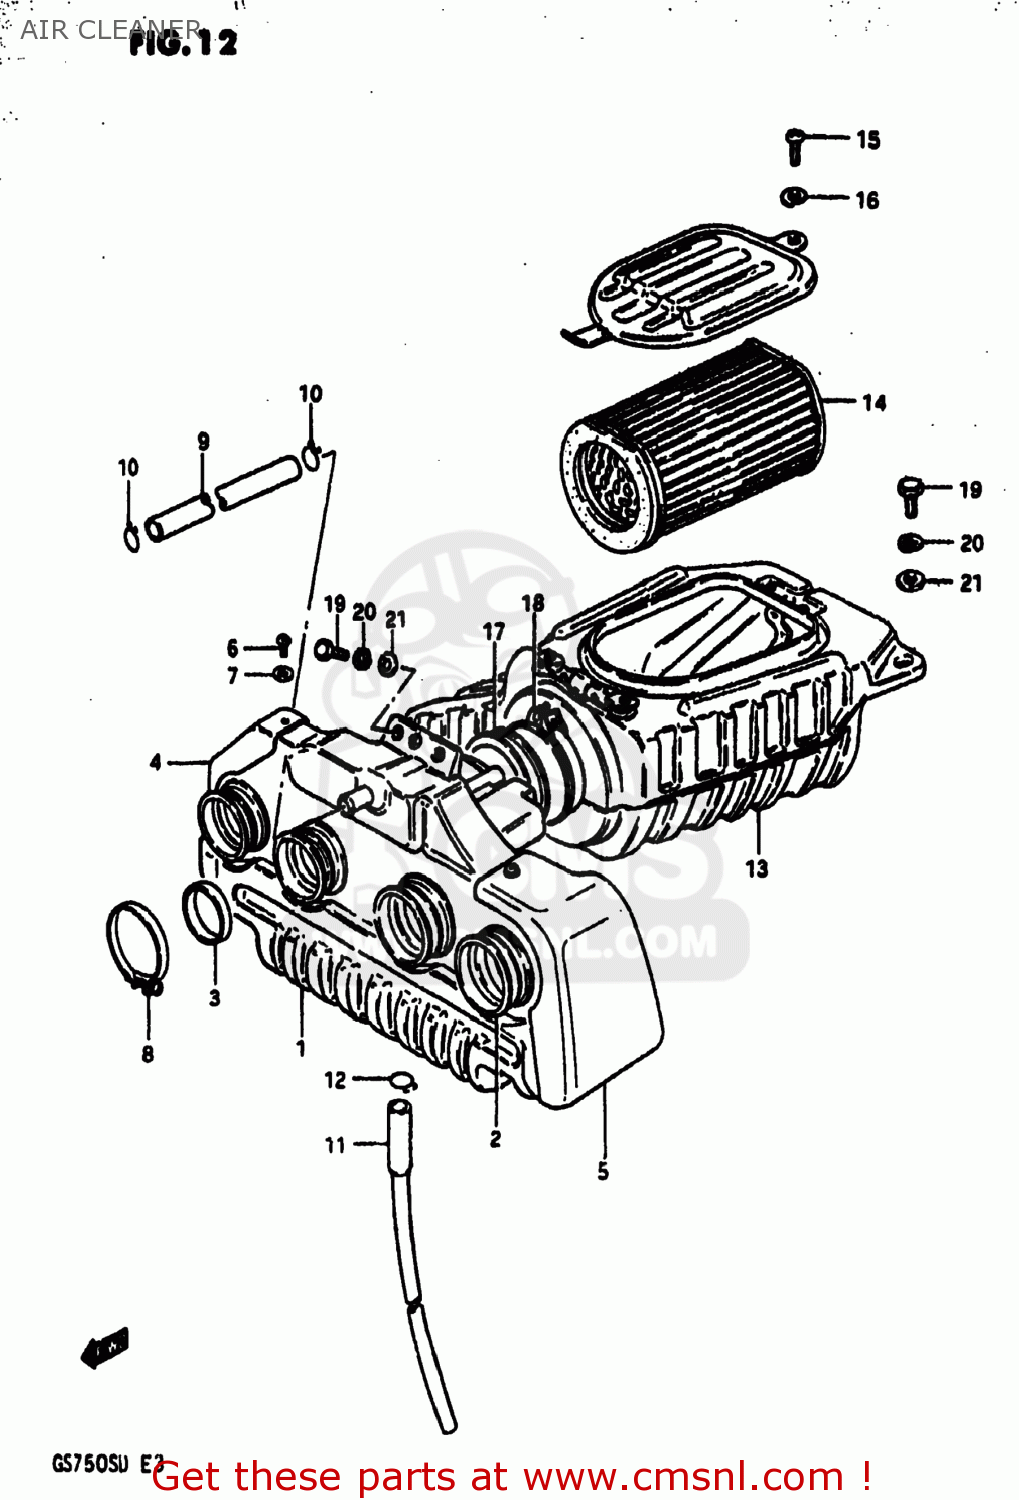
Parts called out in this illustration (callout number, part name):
1	CASE COMP,AIR CLEANER
2	TUBE,OUTLET
3	RING,CARBURETOR AIR INLET HOSE
4	COVER,AIR CLEA
5	COVER
6	SCREW 4X6
7	WASHER
8	CLAMP
9	TUBE,BREATHER
10	CLIP
11	DRAIN TUBE
12	CLIP
13	CLEANER SET,AIR,REAR
14	FILTER,AIR CLEANER
15	SCREW
16	LOCK WASHER
17	HOSE,AIR CLEANER
18	BAND
19	BOLT
20	LOCK WASHER
21	WASHER
